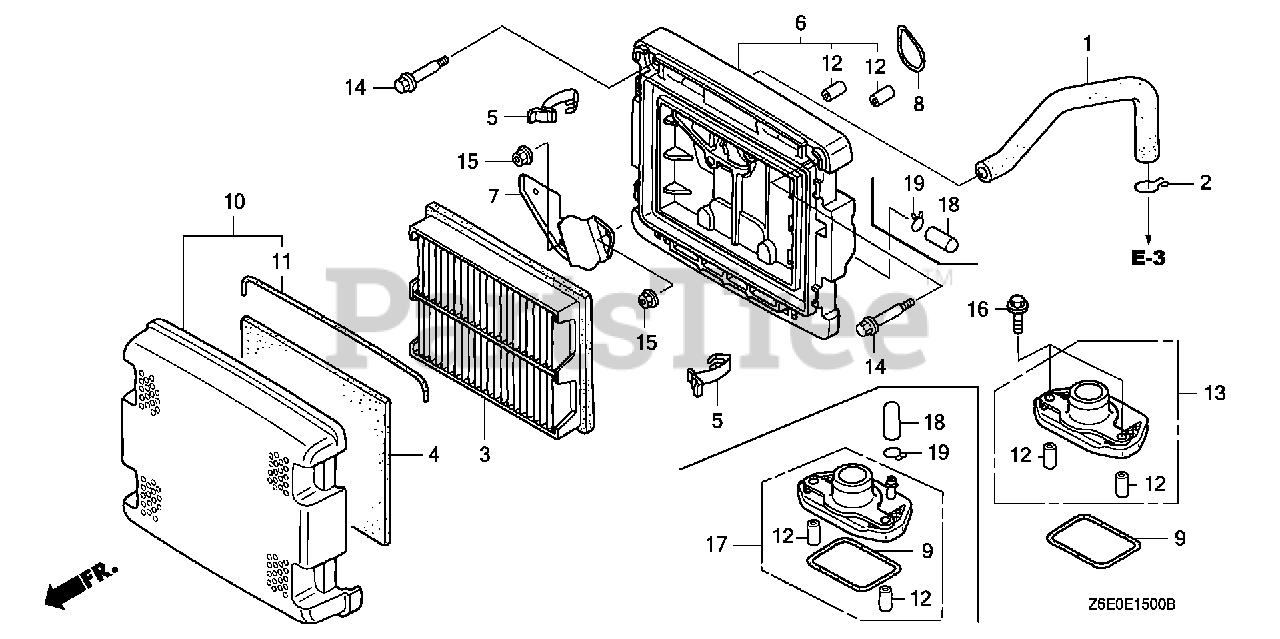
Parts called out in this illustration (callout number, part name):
1	TUBE, BREATHER
2	CLIP, BREATHER TUBE
3	ELEMENT, AIR CLEANER
4	FILTER (OUTER)
5	CLIP, AIR CLEANER
6	HOUSING, AIR CLEANER
7	CAP, AIR CLEANER
8	GASKET, AIR CLEANER
10	COVER ASSY., AIR CLEANER
11	SEAL, AIR CLEANER COVER
12	COLLAR A, AIR CLEANER
14	BOLT, SPECIAL (5MM)
15	NUT, FLANGE (6MM)
18	CAP, SEALING
19	CLIP, TUBE (B10)
